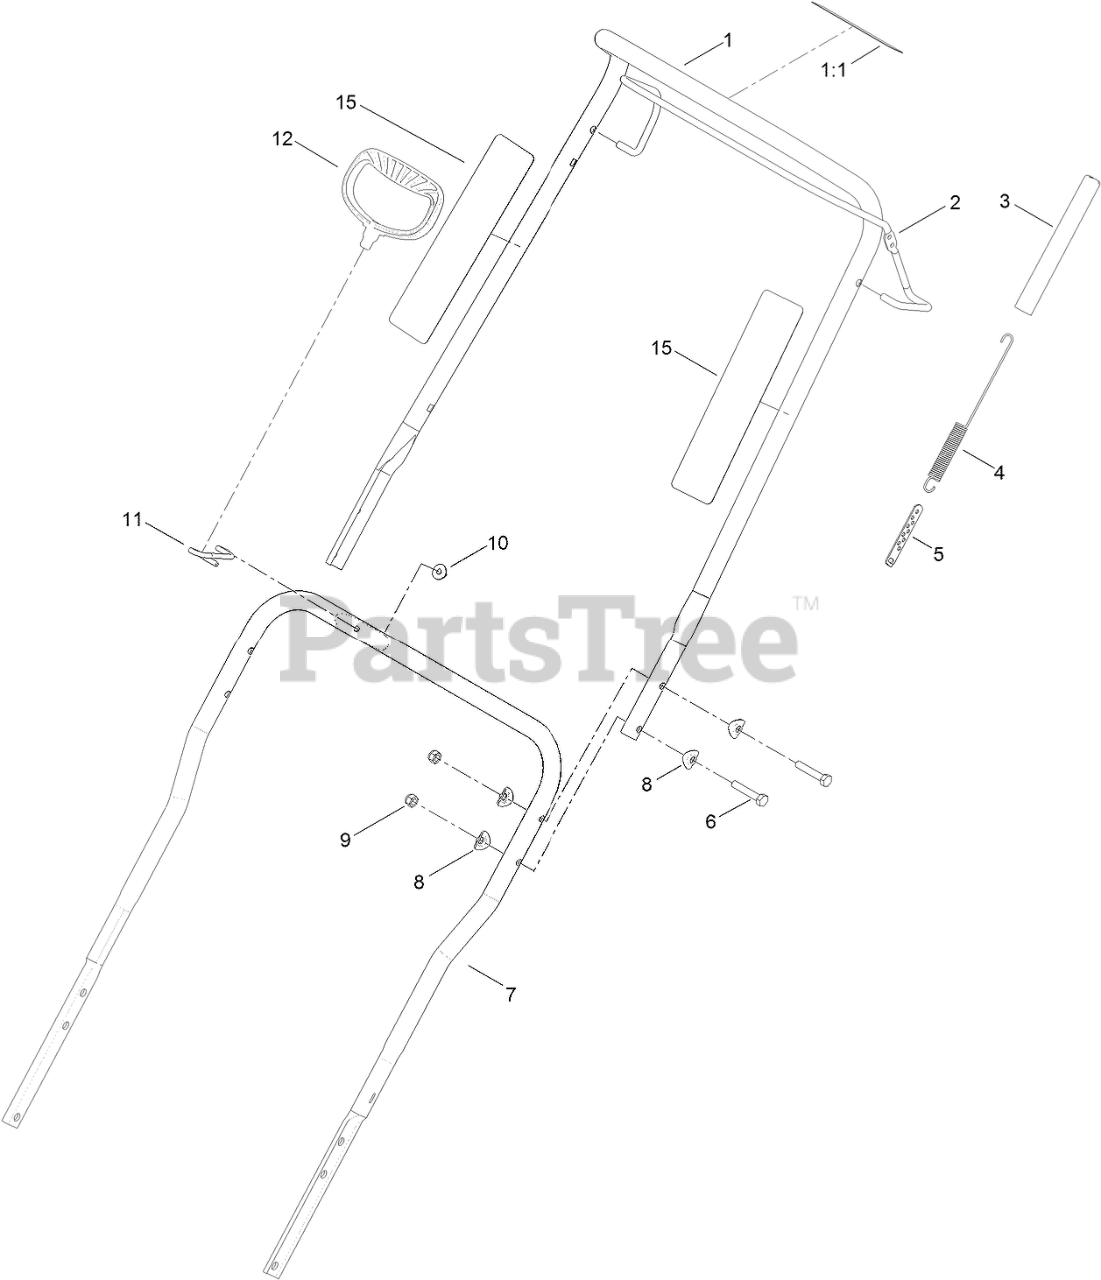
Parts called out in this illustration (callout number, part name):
1	UPPER HANDLE ASM
1:1	DECAL-DRIVE, ROTOR
2	BAIL-CONTROL
3	COVER-SPRING
4	SPRING-EXTENSION, CLUTCH
5	ADJUSTER-CABLE, CLUTCH
6	SCREW-HH
7	HANDLE-LOWER
8	WASHER
9	NUT-LOCK, NI
10	NUT-HEX FLG
11	GUIDE-ROPE
12	HANDLE-RECOIL
15	DECAL-TAPE, REFLECTIVE
